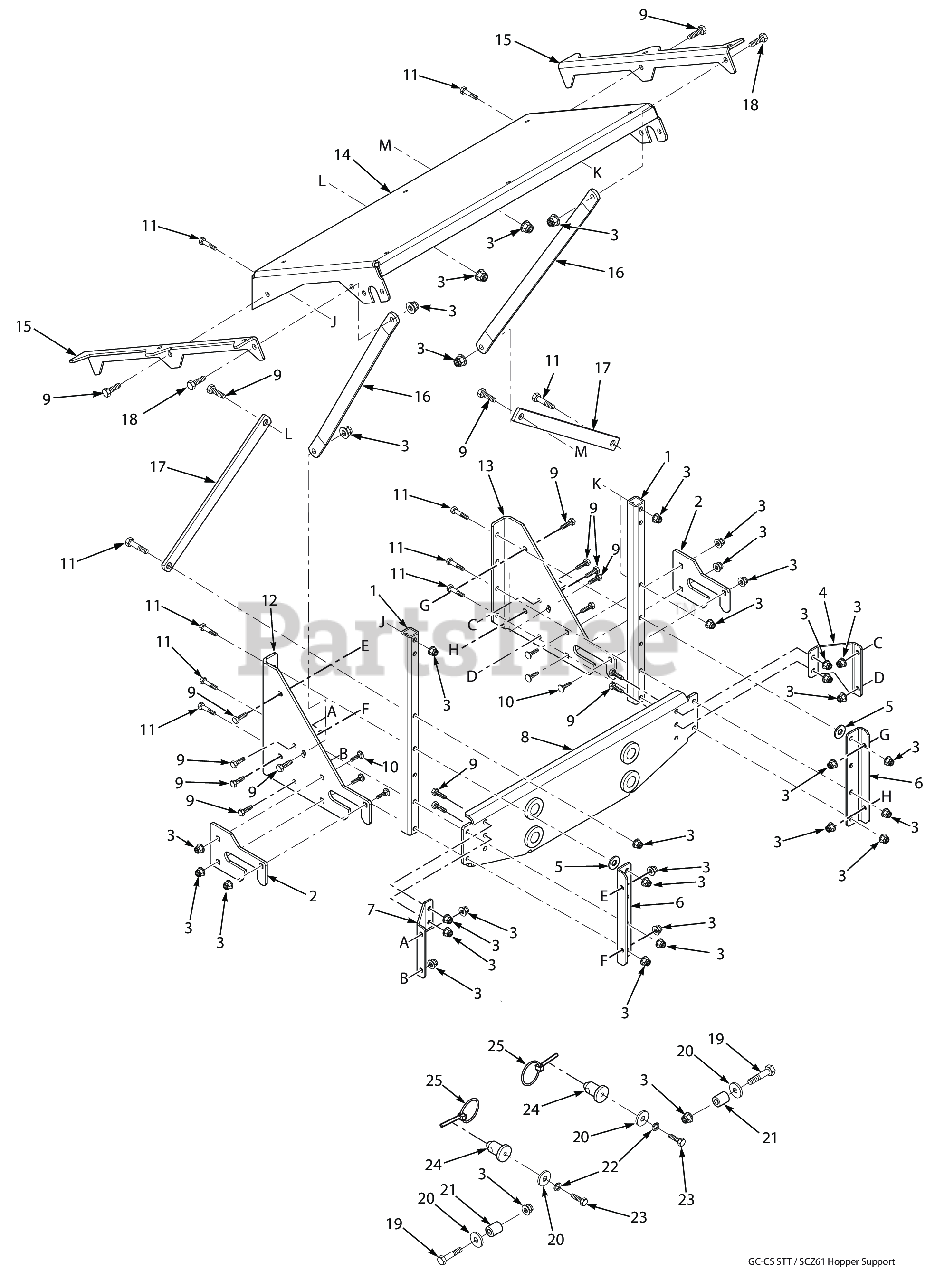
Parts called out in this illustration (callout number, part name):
1	Tube, Upright
2	Wear Plate, GC
3	Nut, Flange Elastic Stop Nut, 3/8-16
4	Angle Brace, LH GC
5	Flatwasher, 7/16-.469 x 1.75 x .25 (48, 52)
6	Mounting Bracket, GC Tube
7	Angle Brace, RH GC
8	Mounting Bracket Weldment
9	Bolt, Hex Head 3/8-16 x 1"
10	Carriage Bolt, 3/8-16 x 1.0"
11	Capscrew, Hex Head 3/8-16 x 2-1/2"
12	RH Mounting Bracket, GC
13	LH Mounting Bracket, GC
14	Support Frame, Hopper
15	Bracket, Hopper Support
16	Brace Stiffener, Short
17	Brace, Engine Mounting
18	Bolt, Hex Head, 3/8-16 x 1 Gr. 5
19	Bolt, Hex Head 3/8-16 x 2-1/4"
20	Flatwasher, 3/8-.406 x 1-1-1/2 x 7 Gauge
21	Spacer
22	Lockwasher, 3/8" Spring, Kawasaki FX / FS
23	Bolt, Hex Head 3/8-16 x 1-1/4", Kawasaki FX / FS
24	Pin, GC Locator
25	Quick Pin, 5/16" Dia.
